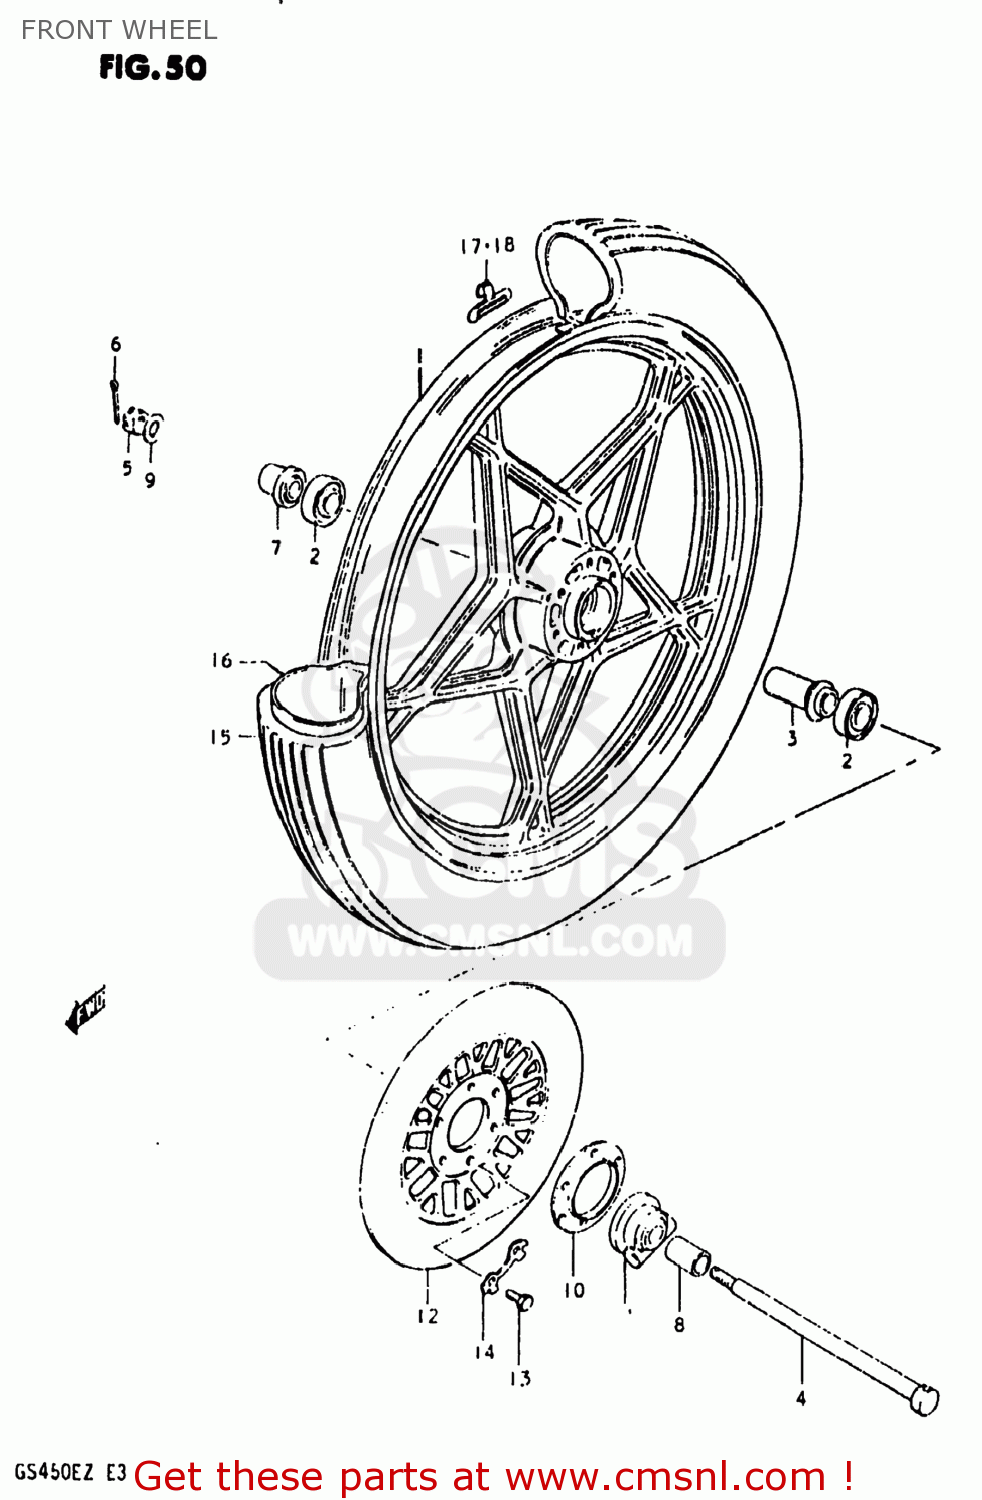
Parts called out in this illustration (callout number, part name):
1	CASTING WHEEL,FRONT 1.60
2	BEARING
3	SPACER(15.3X21.7X63)
4	AXLE,FRONT
5	NUT 12MM
6	COTTER PIN
7	SPACER,FR HUB BEARING,R
8	SPACER(15X22X30)
9	WASHER
10	DUST SEAL,SPEEDOMETER GEAR BOX
11	BOX ASSY,SPEEDOMETER GEAR
12	DISC,FR BRAKE
13	BOLT(8X25)
14	WASHER
15	TIRE,FRONT
16	TUBE,INNER
17	BALANCER,WHEEL
18	BALANCER,WHEEL
